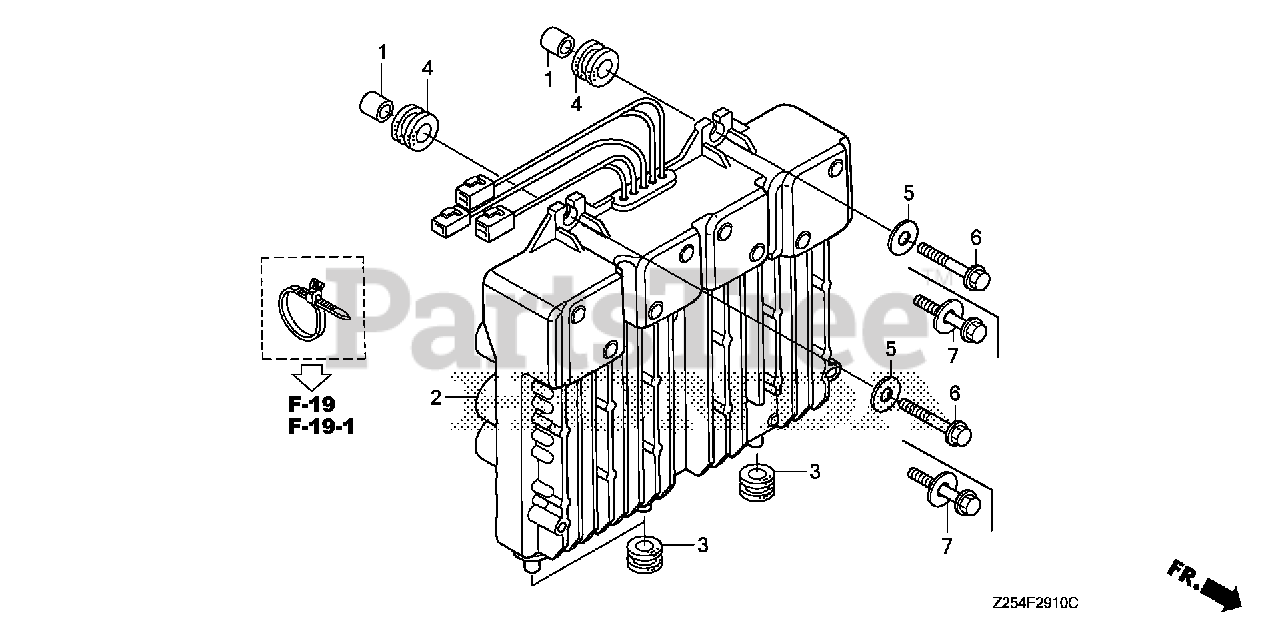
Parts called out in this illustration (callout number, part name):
1	COLLAR, IN. JOINT
2	INVERTER UNIT
3	CUSHION, TANK RUBBER
4	RUBBER, INVERTER UNIT
5	WASHER, PLAIN (6MM)
6	BOLT, FLANGE (6X25)
7	BOLT-WASHER (6X25)
